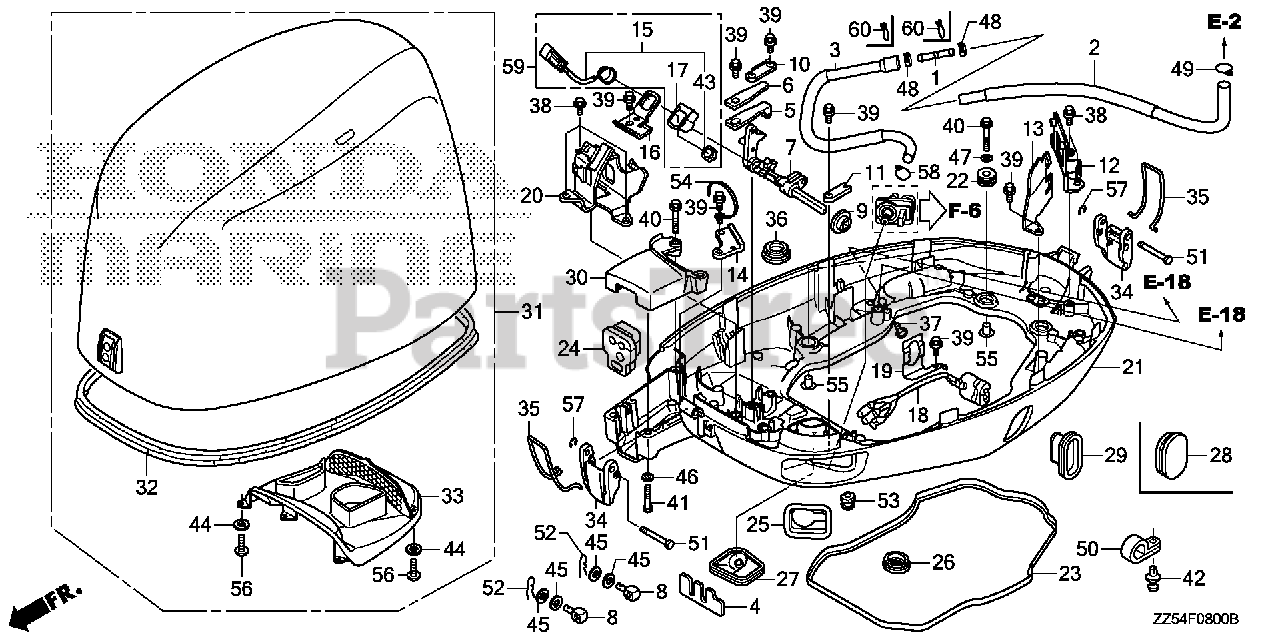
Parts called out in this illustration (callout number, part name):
1	JOINT, FUEL FEED HOSE
2	TUBE A, FUEL (FKM)
2	TUBE A, FUEL
3	TUBE D, FUEL (FKM)
3	TUBE D, FUEL
4	PLATE, REMOTE CONTROL CABLE
5	SPRING, CLICK
6	SPRING, CLICK ASSIST
7	SHAFT, SHIFT
8	PIVOT, SHIFT
9	BUSH, SHAFT
10	PLATE, SHIFT
11	PLATE, SHIFT SHAFT
12	BRACKET, REGULATOR
13	BRACKET B, CONNECTOR
14	BRACKET, CABLE CLIP
15	SWITCH ASSY., NEUTRAL
16	BRACKET, NEUTRAL SWITCH
17	PLATE, NEUTRAL SWITCH
20	BRACKET, MAIN RELAY
21	CASE, ENGINE (LOWER) *NH282MU* (OYSTER SILVER METALLIC-U)
22	GROMMET, CASE (LOWER)
23	SEAL, CASE (LOWER)
24	GROMMET, CASE (LOWER) (A)
25	GROMMET, CASE (LOWER) (B)
26	GROMMET, CASE (LOWER) (C)
27	GROMMET, CASE (LOWER) (E)
28	GROMMET, CASE (LOWER)
30	CASE, SEPARATE *NH282MU* (OYSTER SILVER METALLIC-U)
31	COVER, ENGINE *NH282MU* (OYSTER SILVER METALLIC-U)
32	SEAL, ENGINE COVER
33	GUIDE, ENGINE COVER AIR
34	LEVER, FASTENER
35	WIRE, FASTENER
36	CAP, L. SIDE COVER
37	GROMMET, WATER CHECK
38	BOLT, FLANGE (6X14) (CT200)
39	BOLT, FLANGE (6X12) (CT200)
40	BOLT, FLANGE (6X28)
41	BOLT, HEX. (6X40)
43	NUT, HEX. (20MM) Use up to Frame SN 1300359.
44	WASHER, PLAIN (5MM)
45	WASHER, PLAIN (6MM) Use from Frame SN 4800713.
46	WASHER, PLAIN (6MM) Use up to Frame SN 4800342.
47	WASHER, PLAIN (6MM)
48	CLAMP, TUBE (D12)
49	CLIP, TUBE (B12)
51	PIN (5X44.5)
52	PIN, SPECIAL LOCK (6MM)
53	PLUG, CHANGE REINFORCEMENT
54	CLIP, HARNESS BAND (155.3MM) (BLACK)
55	COLLAR, MODULE IGNITION CONTROL CASE (CDI)
56	SCREW, PAN (5X12)
57	E-RING (4MM)
58	CLIP, TUBE (ENGINE NO.)
58	CLIP, TUBE (B12)
59	SWITCH SET, NEUTRAL
